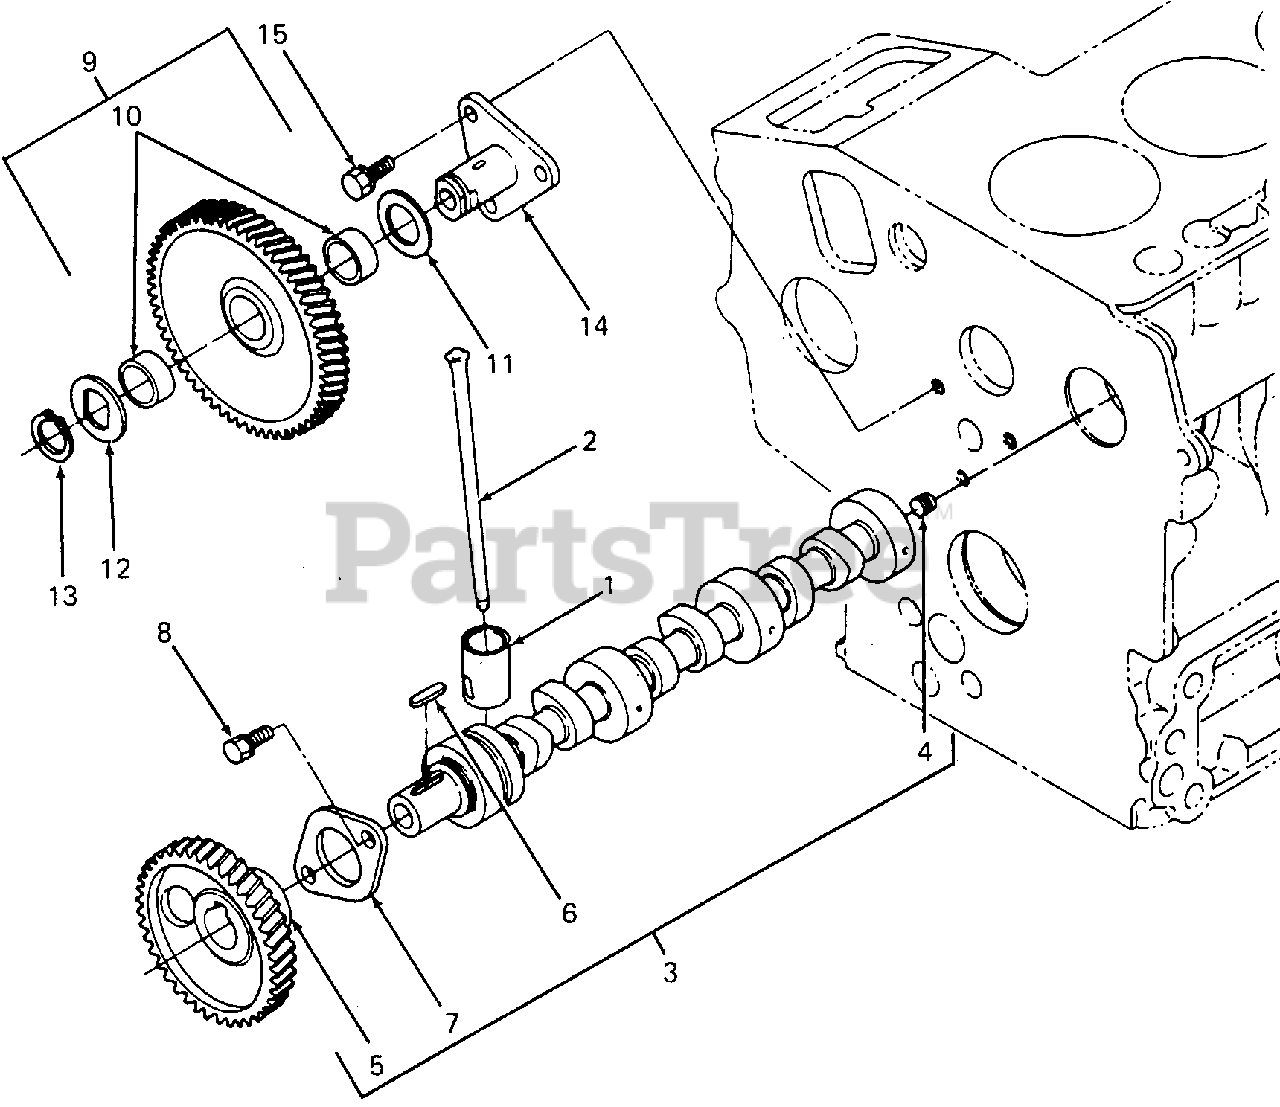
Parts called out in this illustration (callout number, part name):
3	Camshaft w/Gear
5	Gear, Camshaft
7	Stopper, Camshaft
8	Screw, Hex Cap w/Washer
9	Gear Assy, Idler
11	Collar, Idler Gear
12	Collar, Idler Gear
13	Ring, Retaining
14	Shaft, Idler Gear
15	Screw, Hex Cap w/Washer
